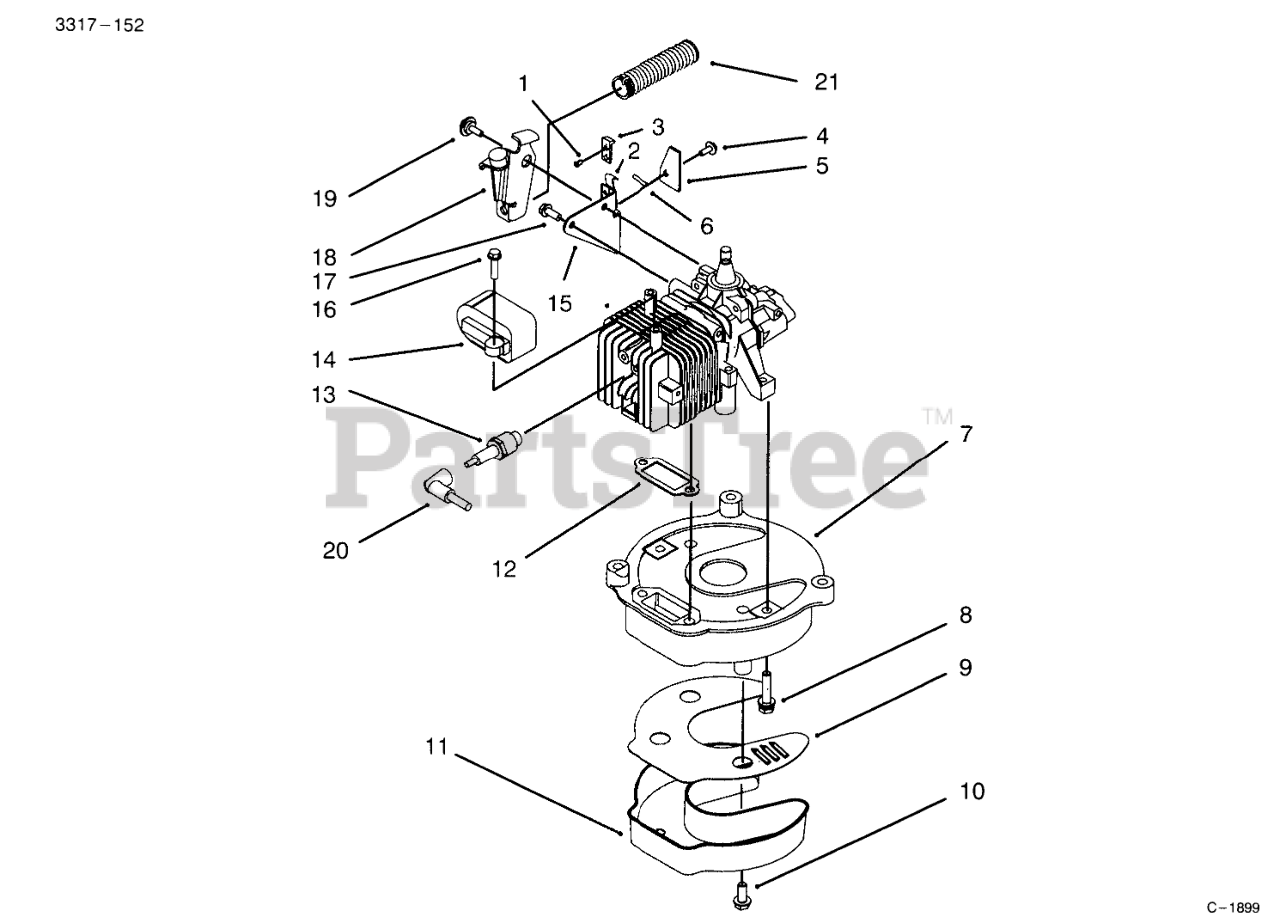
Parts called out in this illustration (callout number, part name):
1	RIVET-PLASTIC
2	STRAP-GROUND
3	STRAP-INSULATION
4	SCREW
5	STOP-GROUND STRAP
6	ELECTRICAL LEAD ASM
7	PLATE-MUFFLER V
8	SCREW V
9	BAFFLE-MUFFLER
10	SCREW
11	Cover-Muffler
12	GASKET-EXH. VF
13	SPARK PLUG
14	Ignition Assembly (Incl. Ref. #20)
15	PLATE-BRAKE
16	SCREW
17	SCREW
18	BRAKE PLATE ASM
19	SCREW-SHOULDER
20	HT LEAD&COVER XEV
21	SPRING-COMPRESSION
